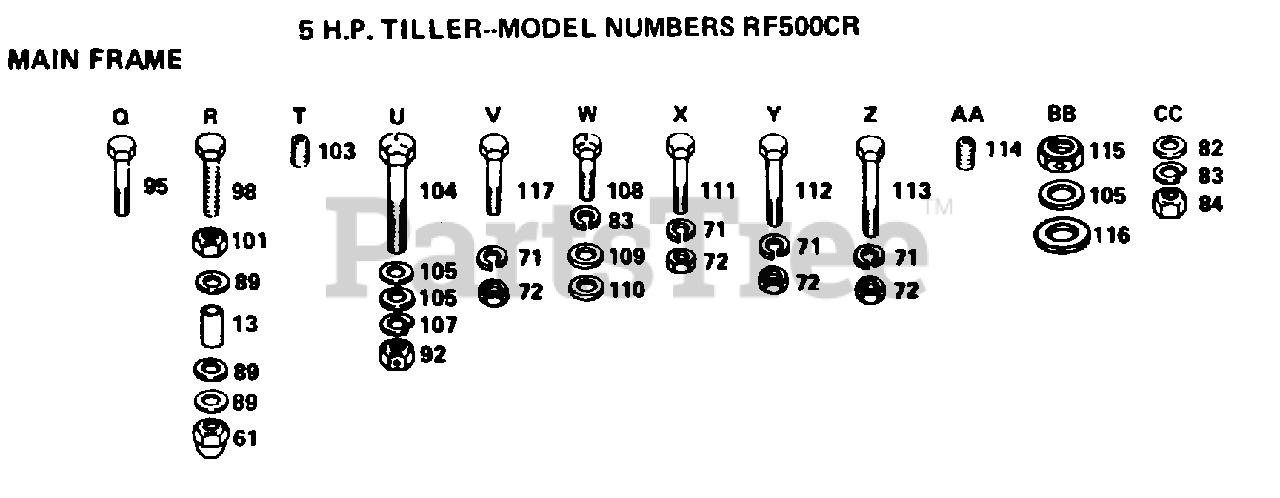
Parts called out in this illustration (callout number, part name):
13	SPACER - SPLIT
71	LOCKWASHER
72	NUT.HEX.5/16-18
82	WASHER
83	LOCKWASHER
89	WASHER
92	GRIPCO NUT
101	NUT.HEX.3/8-16UNC
104	BOLT.3/8-24X3.75
105	WASHER
107	LOCKWASHER
108	BOLT
109	WASHER
110	WASHER
111	BOLT
117	BOLT.HEX.5/16-1.5
